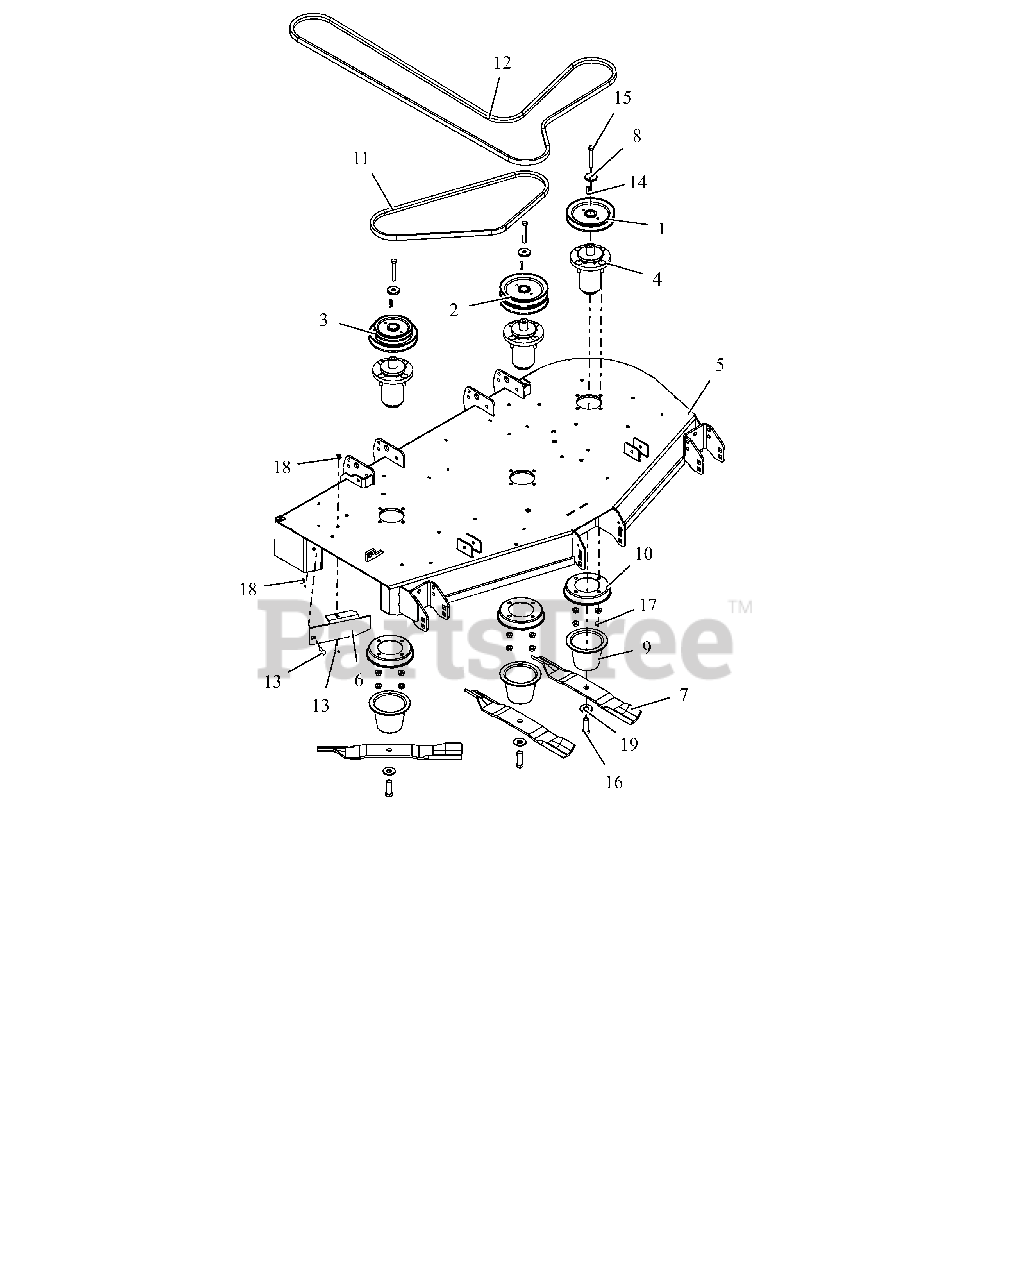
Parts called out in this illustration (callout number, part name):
1	PULLEY, SINGLE-1"ID X 6" OD
2	PULLEY, DOUBLE
3	PULLEY, DBL-1"IDX6.00"&4.75"OD
4	ASM, MAINT FREE ALUM SPINDLE
5	DECK, PT52 W/SAFETY DECALS
6	52" DISCHARGE BAFFLE - RED
7	BLADE, 18.00" MOWER (HI-LIFT)
8	RETAINER, SHEAVE
9	GUARD, SPINDLE LOWER
10	GUARD, SPINDLE TOP
11	V-BELT, B-COGGED
12	BELT, B-SECTI0N EPDM RAW EDGE
13	@BLT-RDHDSQNK .31-18X1.00 G5YZ
14	KEY, SQ .25X.25X1.00 RC 40-50
15	BLT, HEX .38-16X2.75 G8 ZCC
16	BLT, HEX .62-18X1.75 G8 ZCC
17	NUT-LK-CTR-FLG .375-16 GF ZCC
18	@NUT-LK-NYL-FLG .31-18 YWZC
19	WSHR-BLVL .669X1.535X.138
